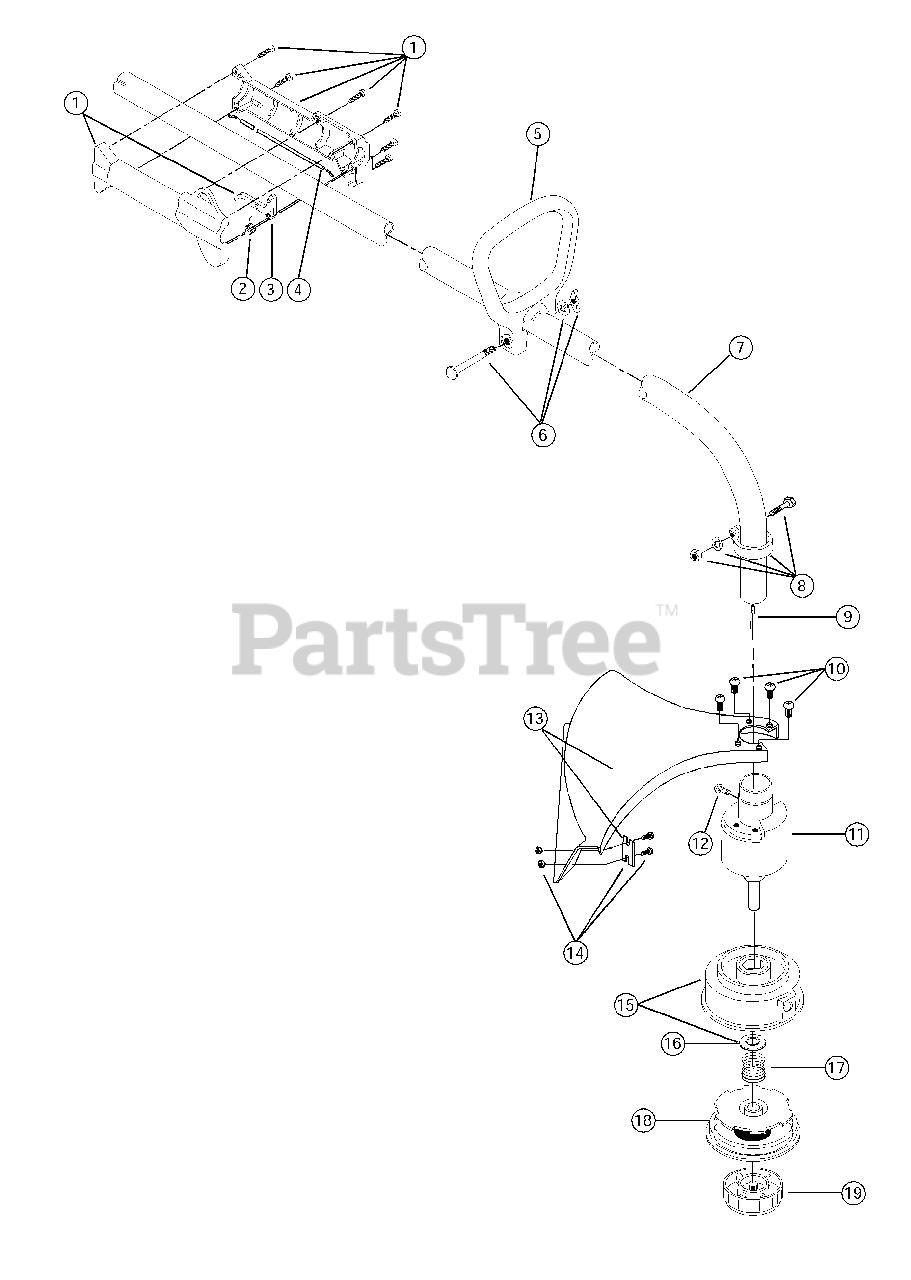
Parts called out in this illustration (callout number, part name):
1	Throttle Housing and Trigger Assembly
2	Throttle Trigger Spring
3	Throttle Trigger
4	Throttle Cable Assembly
5	D-Handle Assembly
6	D-Handle Hardware
7	Drive Shaft Housing Assembly
8	Lower Clamp Assembly
9	Flexible Drive Shaft
10	Shield Mounting Screw
11	Bushing Housing Assembly with Spool Shaft
12	Anti-Rotation Screw
13	Shield and Blade Assembly
14	Blade Assembly
15	Outer Spool and Eyelet Assembly
16	Retainer
17	Spring
18	Inner Reel
19	Bump Head Knob Assembly
